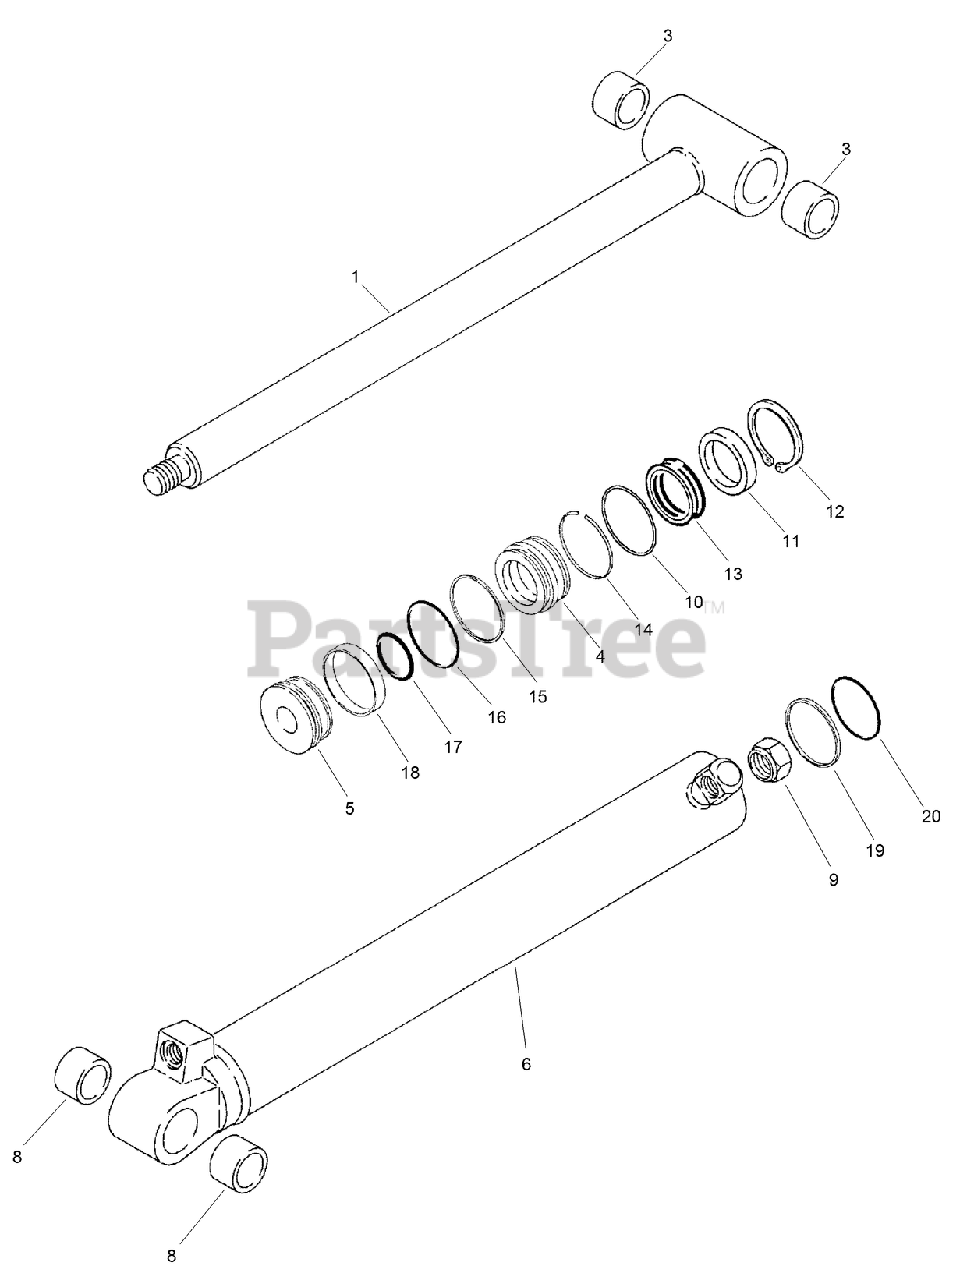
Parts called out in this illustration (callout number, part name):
1	ROD - Piston
3	BUSHING - Piston Rod
4	GLAND - Cylinder
5	PISTON
6	TUBE - Cylinder
8	BUSHING - Piston Rod
9	NUT - 1-1/8
10	RING - Lock
11	WIPER
12	Ring - Retaining
13	SEAL
14	RING - Retaining, Gland
15	RING - Backup, Outer
16	O-RING - 2-3/4 ID x 1/8 inch Wide, Gland, Outer
17	O-RING - 2 ID x 1/8
18	RING - Wear, Piston
19	SEAL - Piston, Piston, Outer
20	O-RING - 2-5/8 ID x 1/8 inch Wide, Piston Seal, Outer
